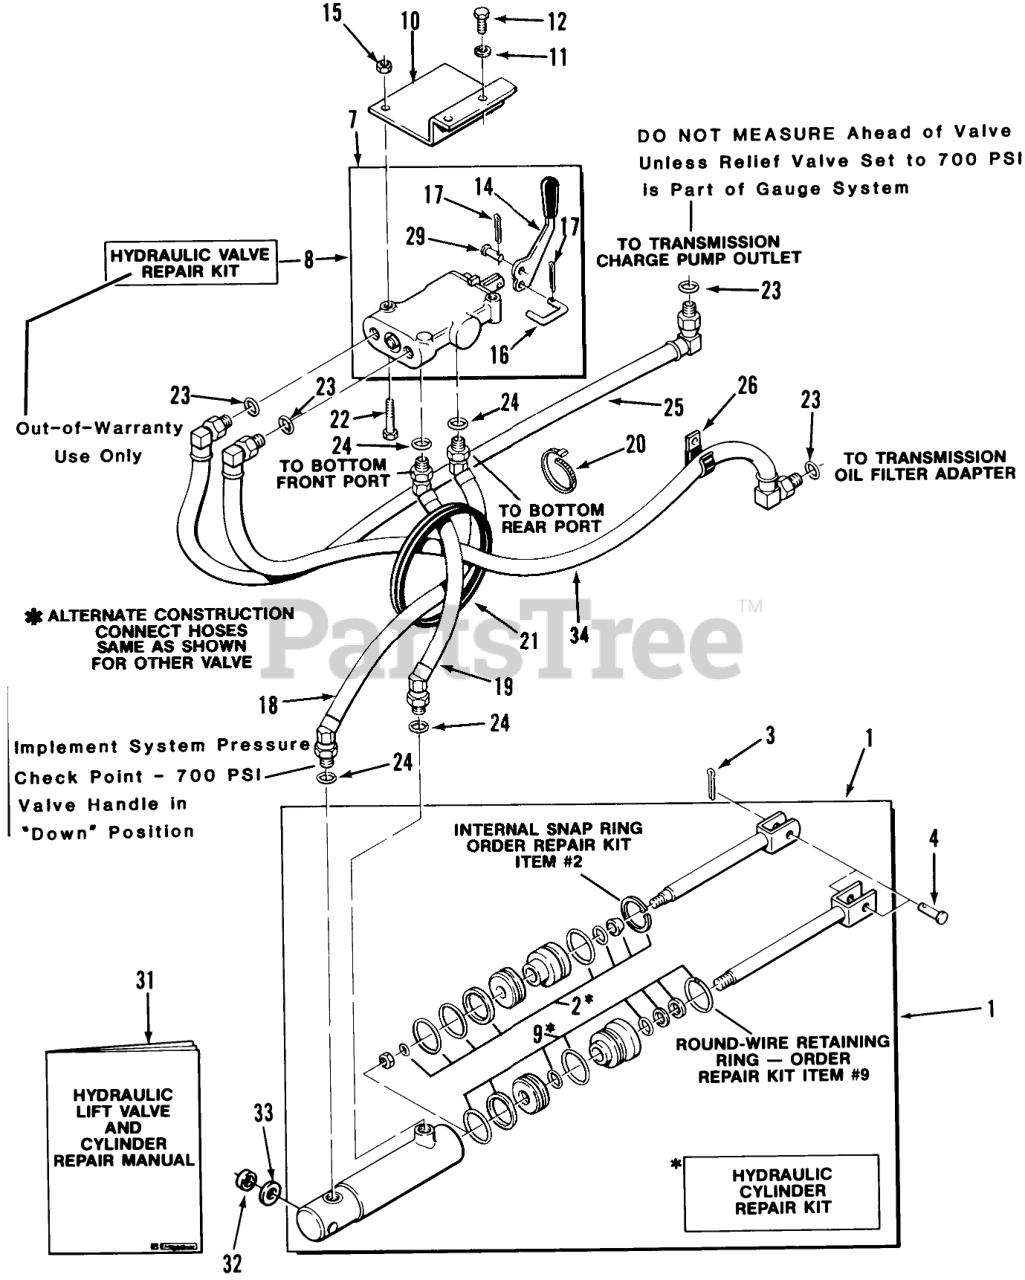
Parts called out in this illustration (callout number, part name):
1	CYLINDER
2	S/A O-RING&GASKET AS
4	CLEVIS PIN
7	Hydraulic Valve
8	S/A 110068 VALVE
9	S/A 108872 HYD CYL
10	ASSY VALVE SUPPOR B
11	Lockwasher
12	Bolt
14	VALVE HANDLE
15	Nut
16	C-HOOK
17	Cotter Pin
18	Hose ASM-Hydraulic
19	Hose ASM-Hydraulic
20	PLASTIC TIE
21	GROMMET
22	Bolt 1/4-20 x 2
23	0-Ring
24	O RING
25	ASSY HOSE HYDRAULIC
26	CLIP
29	Pin
31	Repair Manual
32	Spacer
33	WASHER
34	ASSY HYD HOSE
